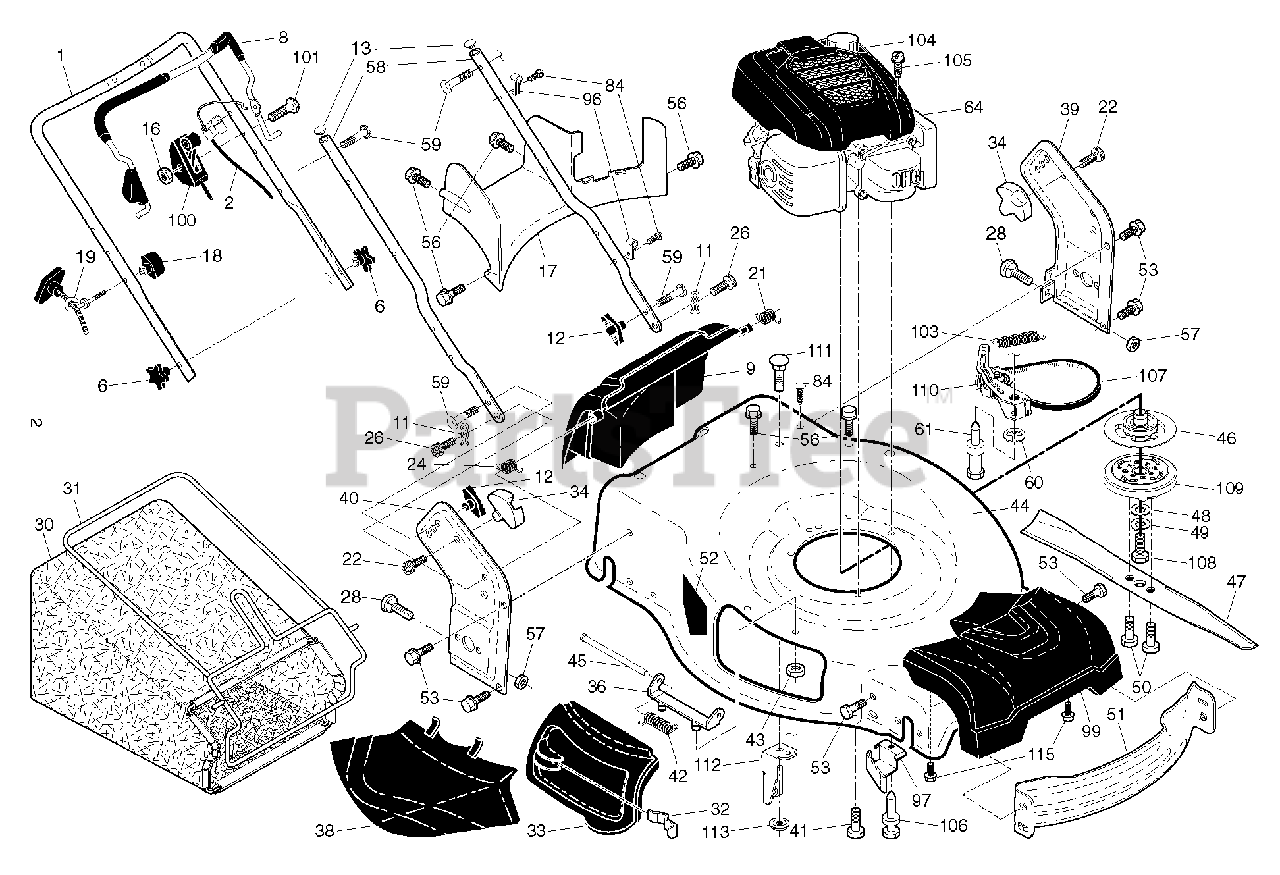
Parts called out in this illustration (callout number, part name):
1	HANDLE.UP.3POS.BS.AW2.GREY
2	CABLE.BBC.22+.AW2.BS.ERGO.WALK
6	KNOB.HANDLE.PLASTIC.STAR.BLACK
8	BAIL.ASM.BBC.EN.ERGO.OM.OR/BK
9	DOOR.REAR.ASM.22+.HUSQ.F/RG.CE
11	COTTER.HAIRPIN.DOOR/HANDLE.PIV
12	KNOB, DEFLECTOR
13	PLUG.PLASTIC.7/8".14-20.GAUGE
16	NUT
17	BAFFLE.REAR.22+RGD.AWD.PLASTIC
18	T-KNOB.NEW ROPE GUIDE
19	GUIDE.ROPE.BLK.ZINC.CHROM
21	SPRING.LH.BLACK
22	SCREW.PAN.HEAD.#10
24	SPRING.RH.GRAY
26	SCREW,DOOR/HANDLE.PIVOT
28	BOLT.CARRIAGE.LN.5/16-18X.5/8
30	GBAG.BA85028ER.GRY/ORG
31	FRAME.GBAG.22+.BLK
32	LATCH.DOOR.ZINC
33	DOOR.MULCH.22 PLUS.HUSQ.GREY
34	BRACKET.GRASSBAG.ATTACHING.BLK
36	BRACKET.ASM.HINGE.21.FWGD.
38	DEFLECTOR.CLIPPING.22.BLACK
39	BRACKET.ASM.HANDLE.LT.22+.GREY
40	BRACKET.ASM.HANDLE.RT.22+.GREY
41	BOLT 3/8-16X1-1/8
42	SPRING.TORSION
43	NUT.FLANGE.1-4-20-SERR
44	HOUSING.22+RG.MC.WO.BBC.668.TR
45	ROD.HINGE.21
46	PULLEY.BBC.DRIVING
47	BLADE.22.4-N-1.BBC.RUST PREV
48	WASHER.CRANK.BOLT
49	LOCKWASHER
50	BOLT.BLADE
51	BAFFLE.FRONT.22.PLUS
52	DECAL.INTERNATIONL.CUTFINGER
53	BOLT.5/16HEX.WHS.HD
56	SCREW.HX.13X.750
57	NUT.FLANGE.5/16
58	HANDLE.LOWER.22+.BT.GRAY
59	BOLT, HANDLE 5/16-18X1.75
60	E-RING.12MM.SHAFT
61	BOLT.BBC.TENSION.PIVOT
84	FASTENER.PUSH.O.250X0.783
96	CLIP.CABLE.BLK
97	BRACKET.BELT.GUIDE.22+.BZP
99	COVER.ASM.FRONT.HUSQ.22+RGD
100	CONTROL.THROTTLE.HOND.BBC.58.5
103	SPRING.BRAKE.RESET
104	SHROUD.ASM.HONDA.HUSQVARNA
105	SCREW.SHROUD.HONDA
106	BOLT.BRAKE.RESET.SPRING
107	BELT.COG.BBC
108	SCREW, HEX HD 3/8-24 X 1-3/8
109	HUB.FREE.BBC.ASSEMBLY(2 2MC)
110	ARM.BBC.TNSION.ARM.PULL(2 2MC)
112	BRACKET.CABLE MOUNTING.22+
113	NUT.FLANGE.1-4-20-SERR
115	SCREW.HI-LO. 5/16 X 1.00
